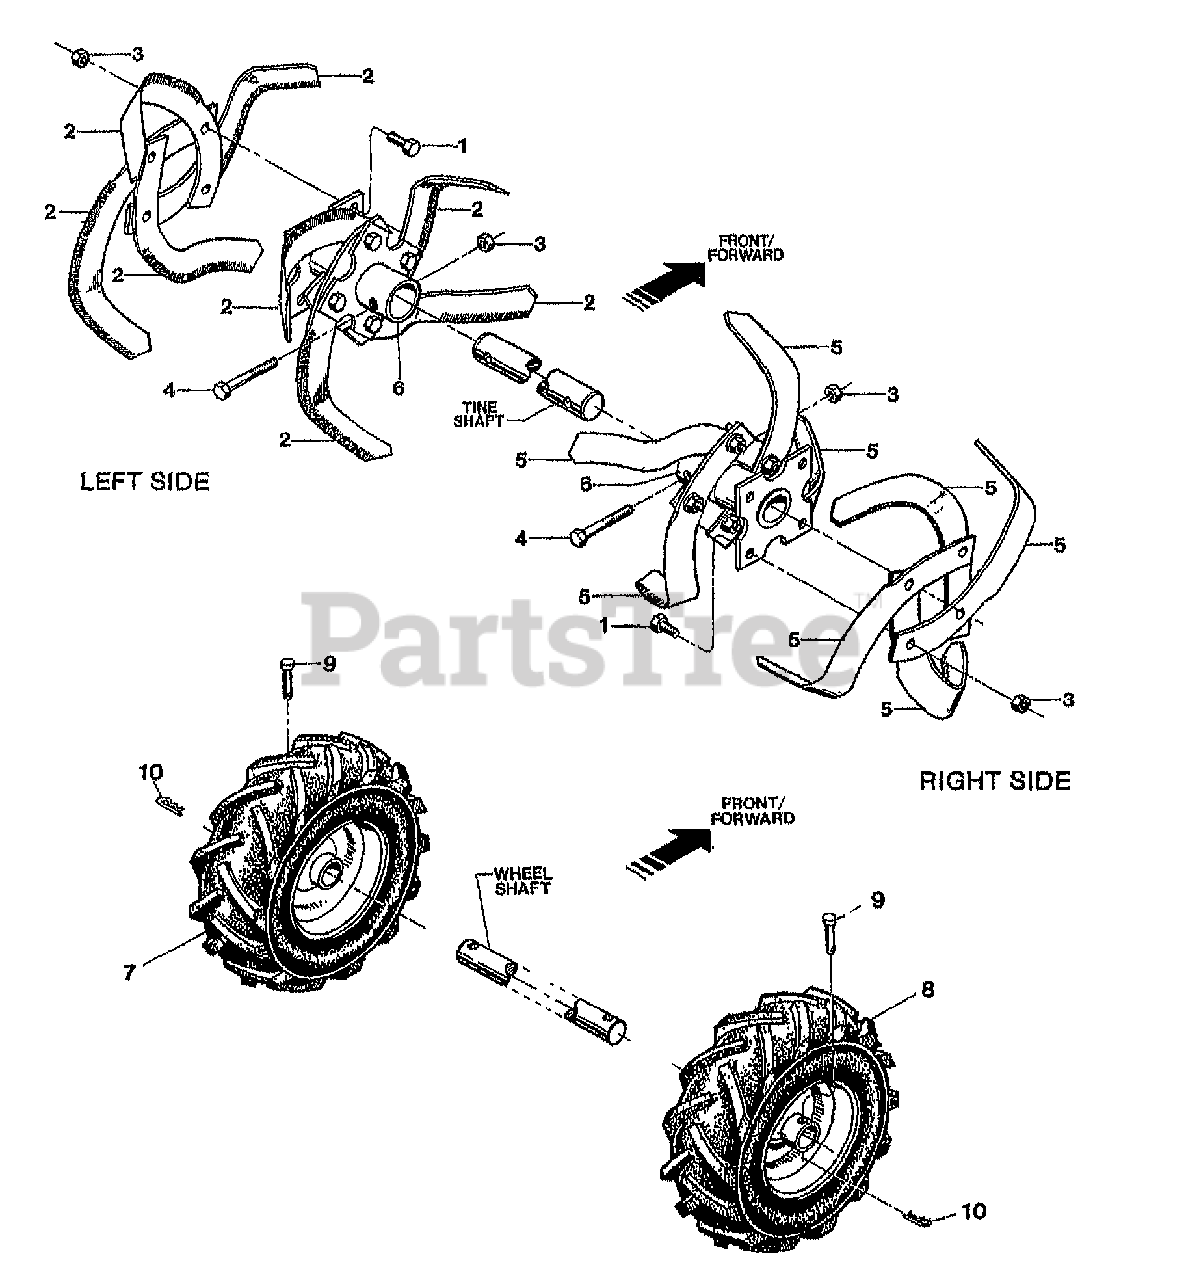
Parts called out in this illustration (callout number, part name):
1	SCR-HH 3/8-16X1.0 G5 ZP
2	TINE-BOLO RIGHT
3	NUT-LOCK 3/8-16
4	SCR-HH 3/8-16X2.00 G8 (TINE HOLDER TO TILLER SHAFT)
5	TINE-BOLO LEFT
6	HOLDER-TINE JUNIOR
6	HOLDER-TINE T/B TUFFY {12155}
7	ASSM-TIRE&WHL LH GRAY
8	ASSM-TIRE&WHL RH GRAY
9	PIN-CLEVIS
10	PIN-CLIP .08
